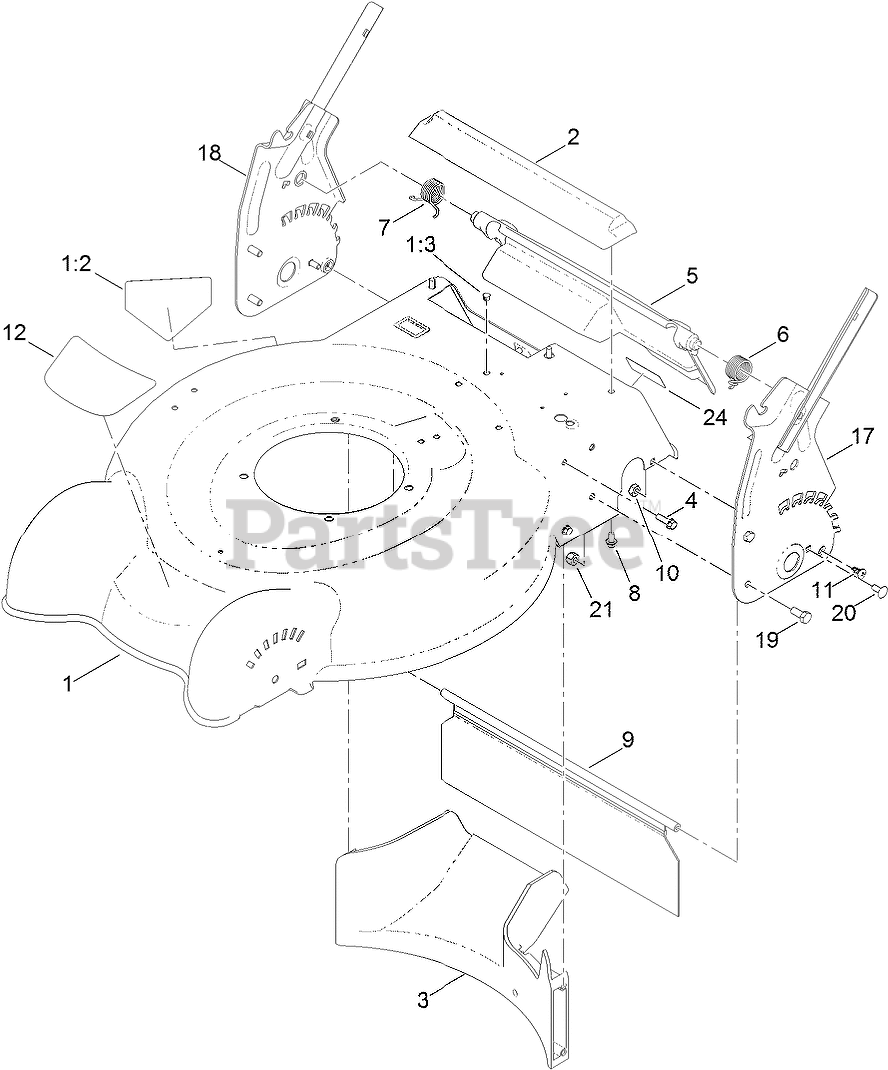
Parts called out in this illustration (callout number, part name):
1	HOUSING ASM
1:2	DECAL-DANGER
1:3	Plug-Dome
2	CHUTE-REAR
3	BAFFLE-REAR
4	SCREW-HWH
5	Rear Deflector ASM
6	SPRING-TORSION, LH
7	SPRING-TORSION, RH
8	SCREW-PLASTITE
9	SHIELD-TRAILING
10	NUT-LOCK, NI
11	SCREW-PTH
12	Decal-Deck
19	SCREW-HH
20	SCREW-CARR
21	NUT-LOCK, NI
24	DECAL-LOCATION, SERVICE DEALER
